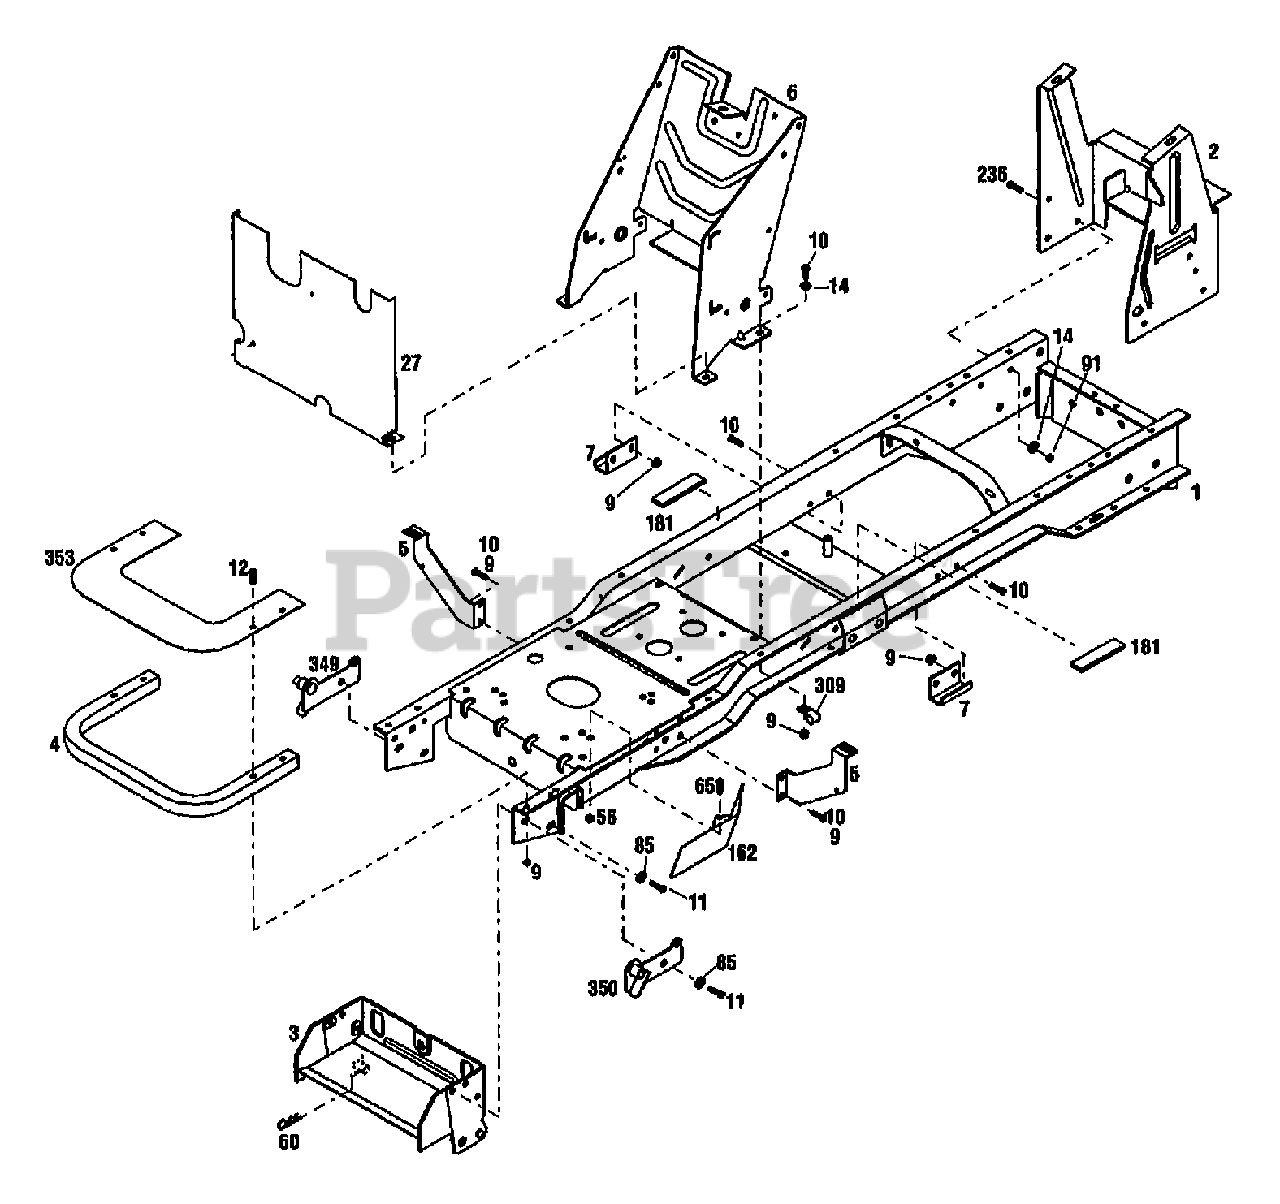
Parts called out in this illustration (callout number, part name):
1	ASSM-FRAME LTX
2	SUPPORT-REAR TANK
3	ASSM-BRKT ATTACHMENT
4	BUMPER-FRONT
5	SUPPORT-FENDER
6	SUPPORT-CONSOLE
9	NUT-HFLK 5/16-18 ZP
10	SCR-HHC 5/16-18X.75 GR 5 ZP
11	SCR-HH 3/8-16X1.0 G5 ZP
12	SCR-HH 5/16-18X1.75
14	WASHER-FLAT 5/16 SAE
27	SHIELD-HEAT
56	NUT-HF/LK 1/4-20 ZP
60	PIN-HITCH .125X2.56 ZP
65	SCR-HH 1/4-20X.625
85	WASHER-FLAT 3/8 SAE
91	NUT-TOP/LK 5/16-18 ZP
162	SHIELD-HEAT UPPER
236	SCR-HFLK 5/16-18X.75 ZP
309	CLIP-J
349	PLATE-PIVOT RH
350	PLATE-PIVOT LH
353	SHIELD-HEAT (13086)
